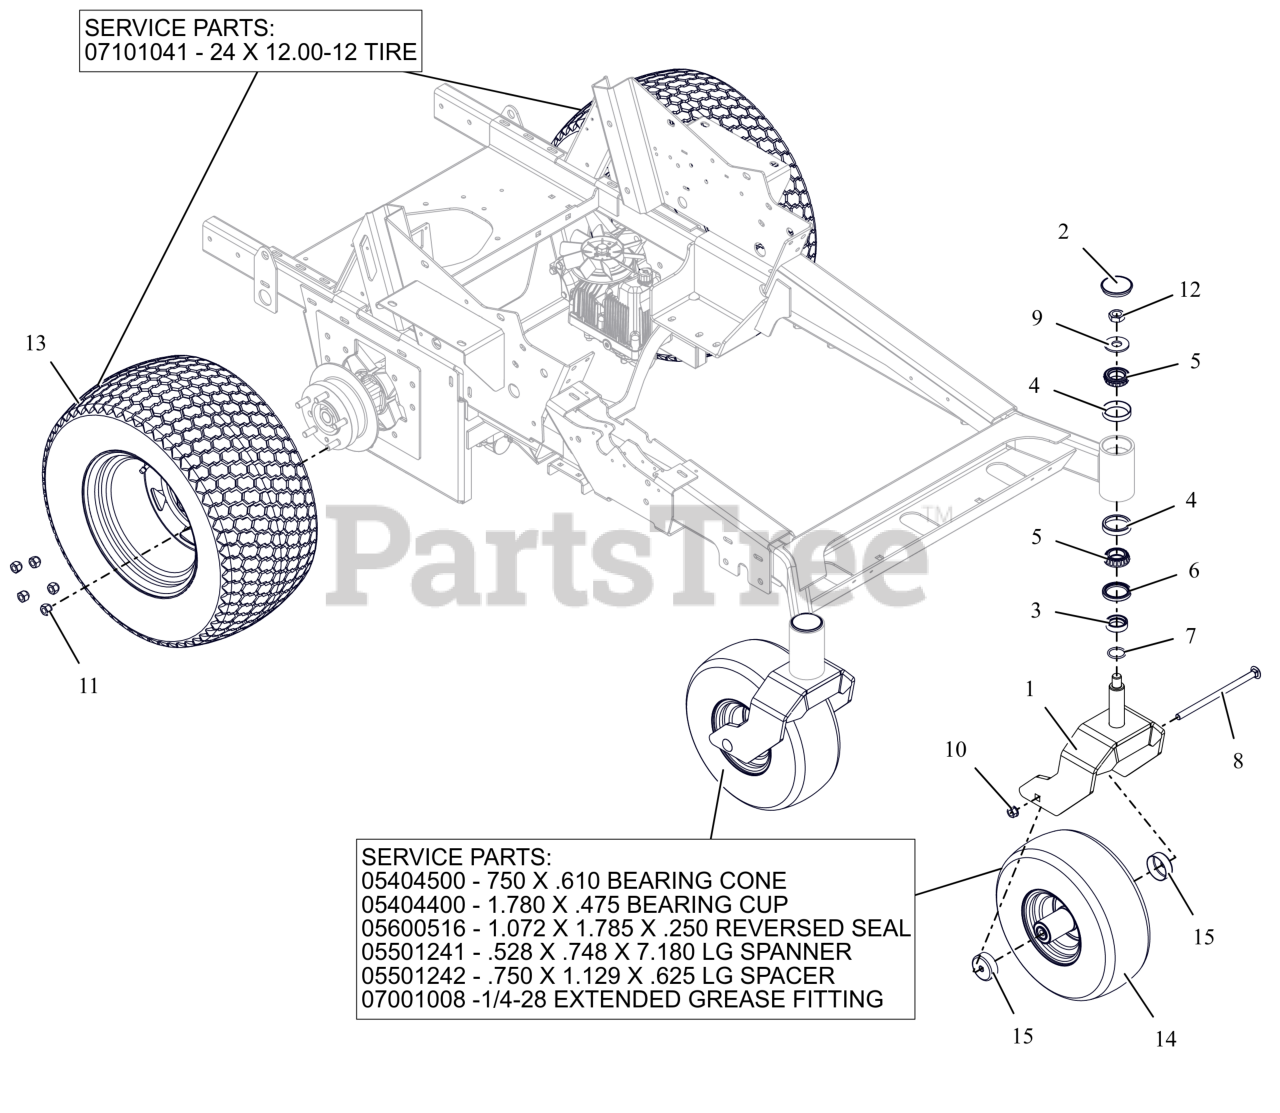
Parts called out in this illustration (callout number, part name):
1	WLDMT, CASTER FORK (RED)
2	CAP, DUST
3	SPCR, FRONT CASTER FORK
4	BRG-CUP 2.328X.465
5	BRG-CONE 1.25X.66
6	SEAL, OIL 1.75 X 2.332 X .312
8	BTL,RHSN .500-13 X 9 G5 ZCC
9	WSHR-FL-STL 0.812X2X0.148 ZCC
10	NUT-LK-CTR-FLG .500-13 GG ZCC
11	NUT, WHEEL .50-20 ZCC
12	NUT, JAM-TOPLOCK .750-16 ZCC
13	ASM-WHL/TIRE24X12.0-12 BLK RIM
13	TIRE, 24 X 12.00-12
13	TUBE 22,23&24X8.50/9.50/10.00/10.50/12.00-12
14	ASM, TIRE/WHEEL 15 X 6.00-6 SEMI
14	BRG-CONE .750X.61
14	BRG-CUP 1.781X.475
14	SEAL,1.072X1.785X.250 REVERSED
14	SPANNER, .528X.748X7.18 LG
14	SPACER, .750X1.129X.625 LG
14	GREASE FITTING 1/4-28 EXTENDED
14	TUBE 15X6-6
15	SHIELD, WHEEL BEARING
